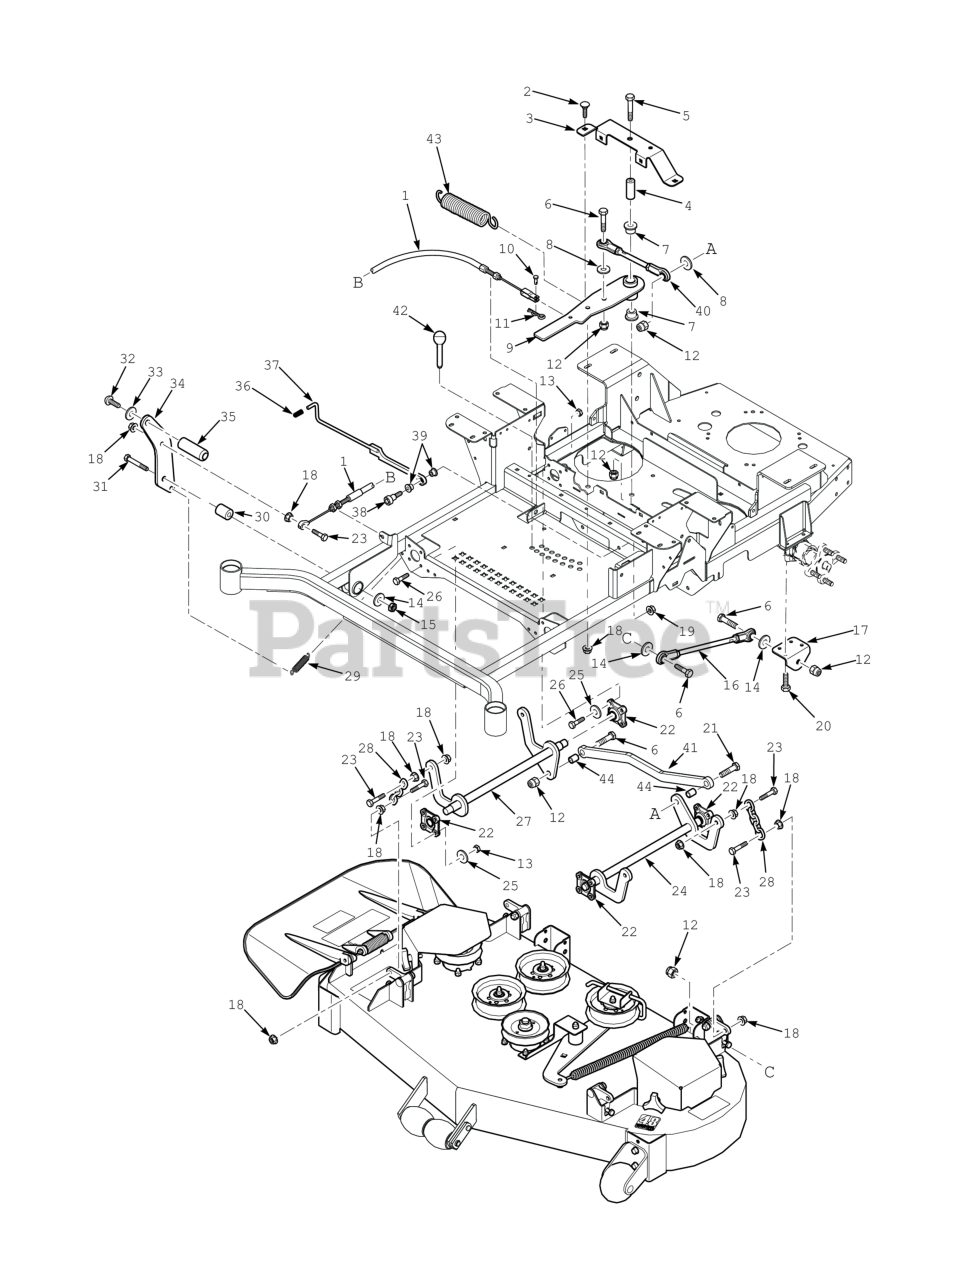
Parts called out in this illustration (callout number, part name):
1	Cable, Deck Lift
2	Bolt, Carriage 3/8-16 x 3/4"
3	Support, Idler Arm
4	Spacer, Deck Lift Pivot
5	Bolt, Hex Head, 1/2-13 x 3-1/4"
6	Hex Head Bolt, 1/2-13 x 2"
7	Bearing, Plastic
8	Flatwasher, 1/2 - .531 x 1.062 x .095
9	DECKLIFT BELLCRANK ASSY, SFZ
10	Clevis Pin, 5/16 x 3/4"
11	COTTER PIN, HAIR - 0.94 X 1.62
12	HEX LOCKNUT, ELASTIC STOP, 1/2-13
13	Nut, Flange Head Elastic Stop 5/16-18
14	Flat Washer, 1/2 (.562 x 1.375 x .109)
15	HEX NUT, ELASTIC STOP LOCK, 3/8-16
16	Linkage, Push Arm
17	Bracket, Push Arm Link
18	NUT, 3/8-16 SERRATED FLANGE HEX HEAD
19	HEX NUT, ELASTIC STOP LOCK, 3/8-16
20	Bolt, Hex Head 5/16-18 x 3.00"
21	Bolt, Hex Head 1/2-13 x 3"
22	Bearing, Deck Lift - 48V & 52V
23	Bolt, Hex Head 3/8-16 x 1-1/2" B&S 32BV
24	Weldment, Deck Lift LH
25	Flatwasher, 1/4" (.312 x .750 x .065")
26	Bolt, Heax Head 5/16-18 x 1" (48V / 52V)
27	Weldment, Deck Lift RH
28	Chain, Deck Lift
29	Spring, Deck Lift
30	Spacer, Deck Lift Pivot
31	Bolt, Hex Head 1/2-13 x 3"
32	Bolt, Head Socket 5/8-11 x 1-1/2"
33	Lockwasher, 5/8" Spring
34	Pedal, Foot Bracket
35	Foot Pedal, Height Adjustment
36	Grip, Deck Latch
37	Weldment, Deck Latch
38	Bolt, Shoulder 1/2 x 1/2"
39	Bearing
40	Linkage Assembly, Deck Lift
41	Mounting Bracket, Fuel Tank Front
42	Pin, Height Adjuster
43	Spring, Deck Lift
44	Sleeve
